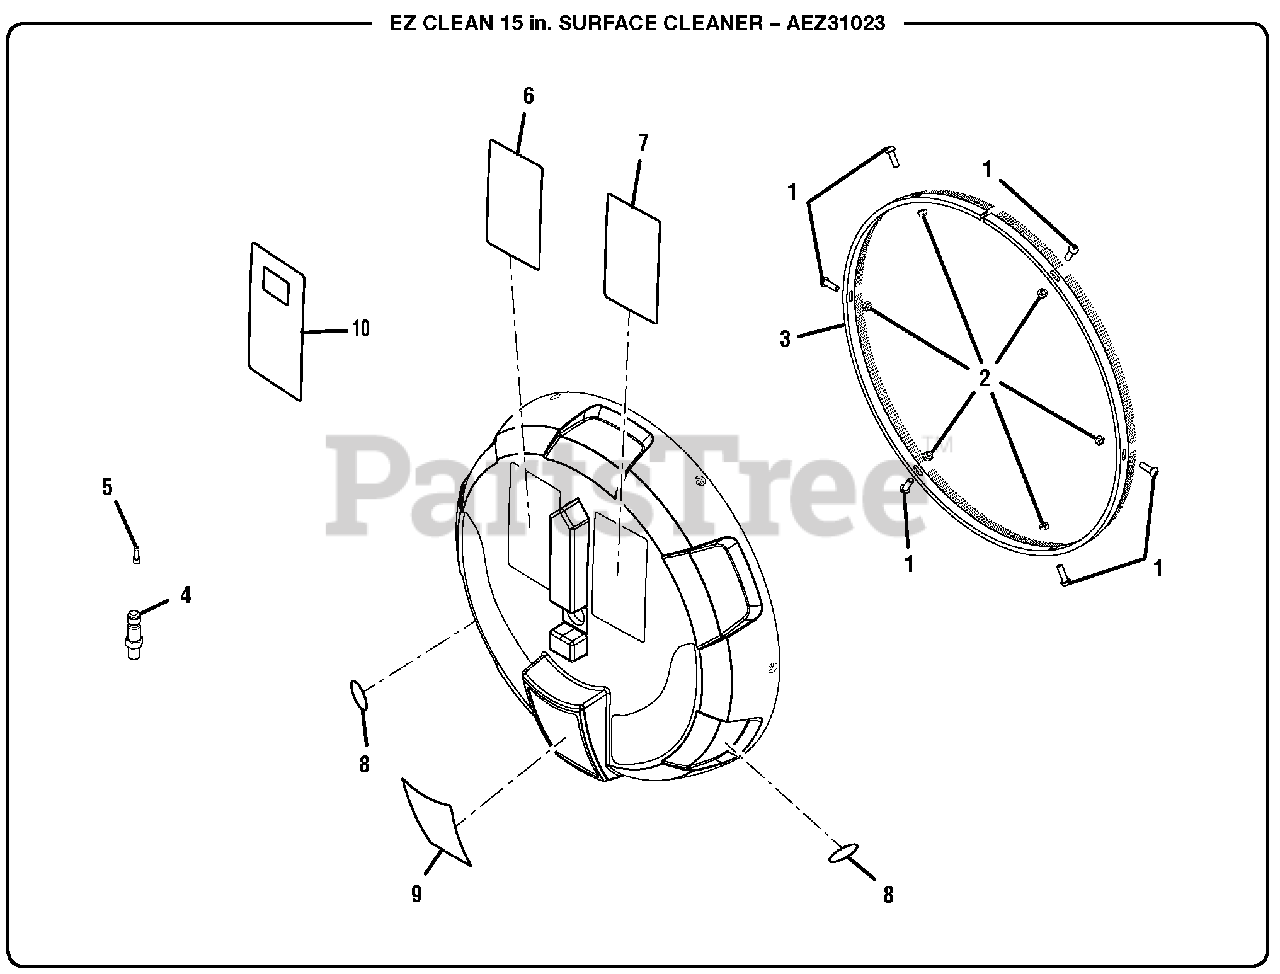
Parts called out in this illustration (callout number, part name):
1	Bolt (M5 x 16 mm, Pan Hd.)
2	Lock Nut (M5)
3	Deck Brush Skirt
4	1/8 in. Quick Connect
5	Inlet Filter
6	Danger Label
7	Danger Label (French)
8	No Hands Label
9	Logo Label
10	Hang Tag Danger Label
